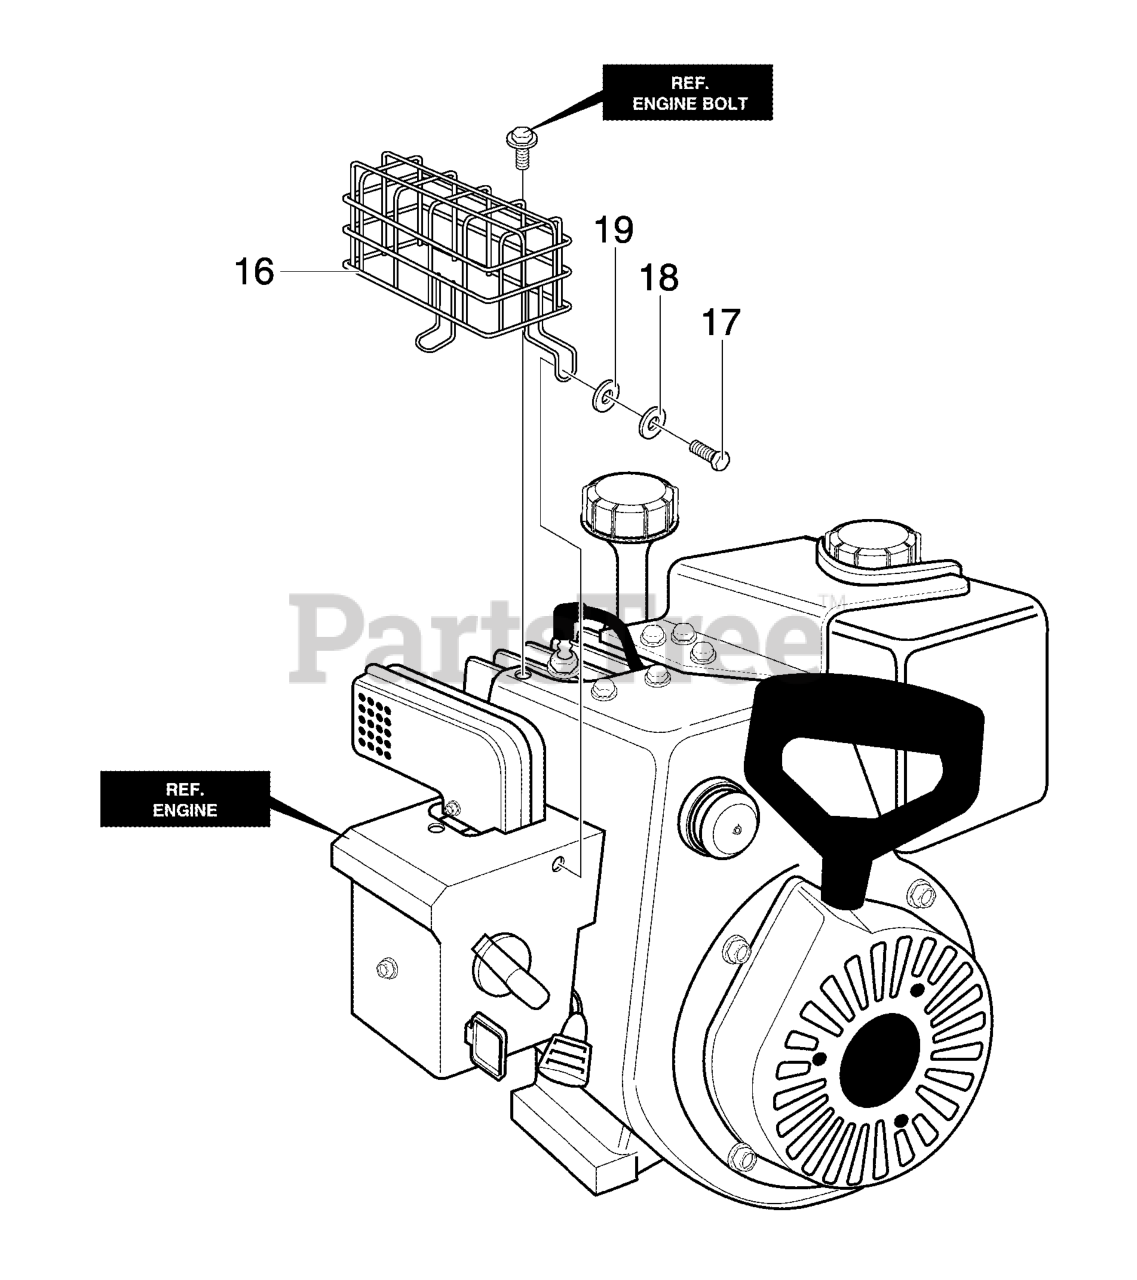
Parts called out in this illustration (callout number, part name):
16	GUARD, MUFFLER
18	WASHER
19	WASHER
